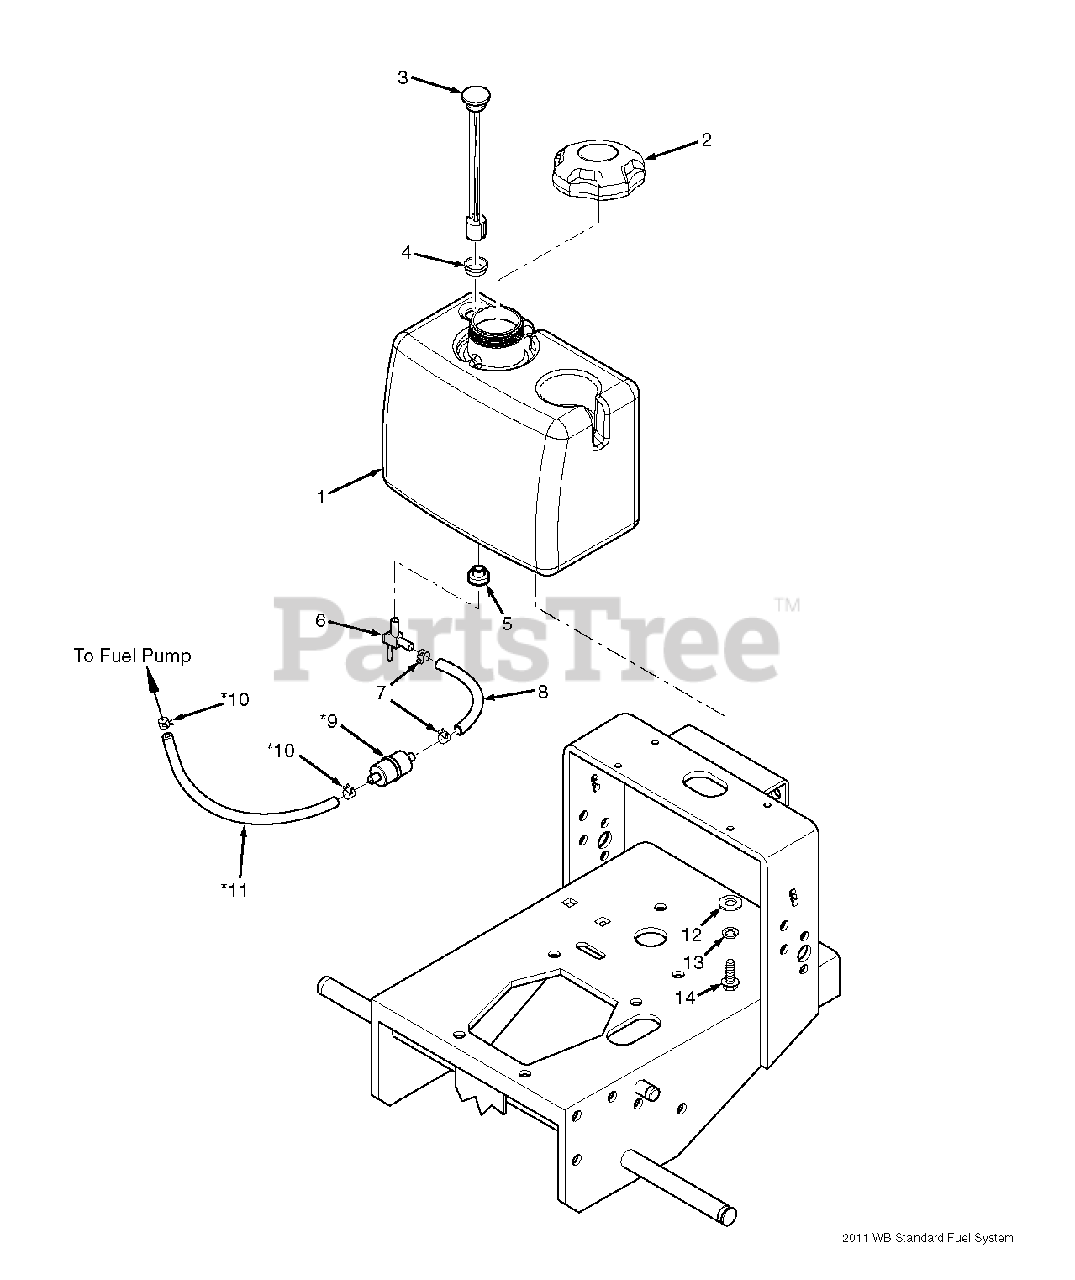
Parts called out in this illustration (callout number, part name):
1	Fuel Tank Assembly
2	Fuel Cap
3	Fuel Gauge Assembly
4	Seal, Fuel Gauge
5	Bushing, .56 Dia. Viton
6	Ball Valve w/Screen
7	Clamp, Fuel Hose
8	Fuel Hose, 1/4" ID
9	Fuel Filter
10	Clamp, Fuel Hose
11	Fuel Hose
12	Flatwasher, 5/16-.375 x .875 x .083
13	Lockwasher, 5/16" Spring
14	Bolt, Hex Head 5/16-18 x 1"
